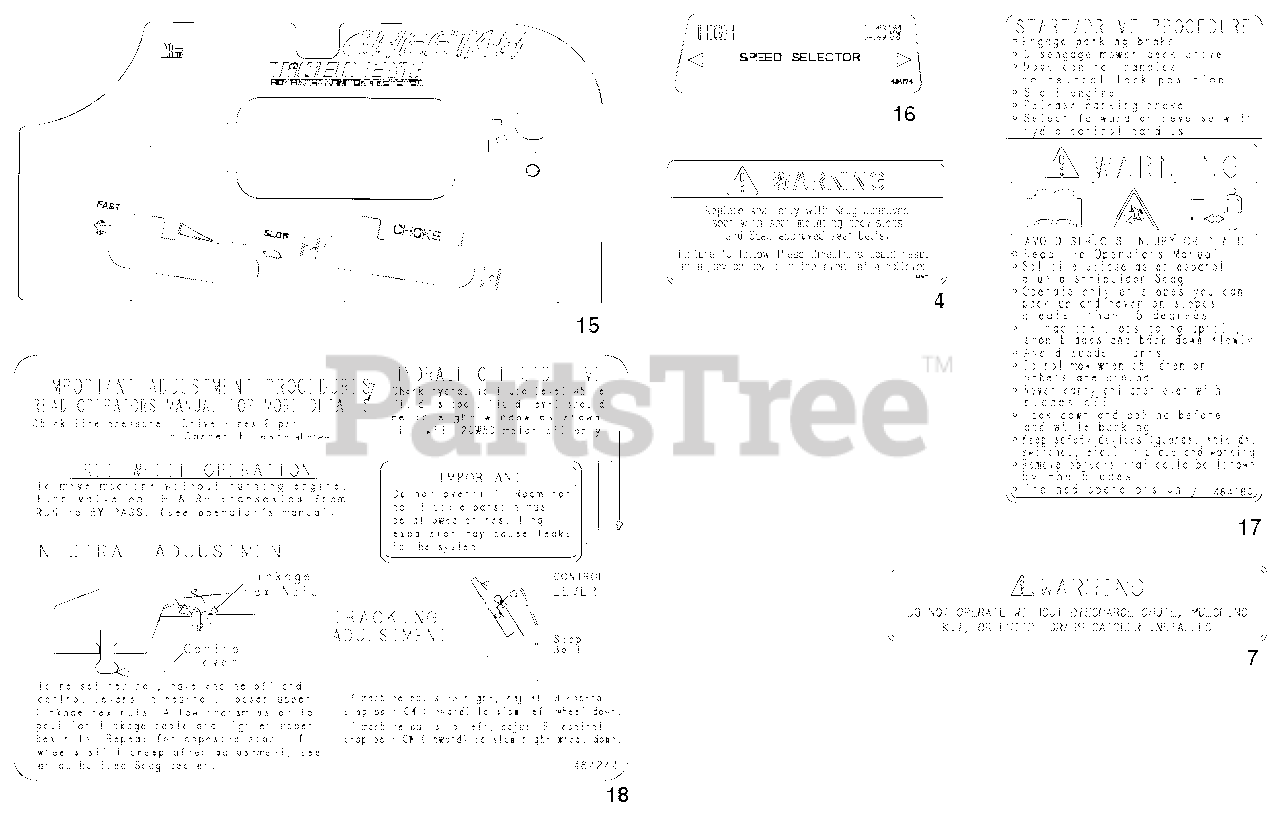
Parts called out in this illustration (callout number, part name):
4	Decal, Seat Replacement
7	Decal, Warning
15	Decal, Instrument Panel - SCZ
15	Decal, Instrument Panel - SCZ - EFI
15	Decal, Speed Control
16	Decal, Start / Drive
17	Decal, Adjustments - SCZ
18	Decal, SCZ Replacement Parts
